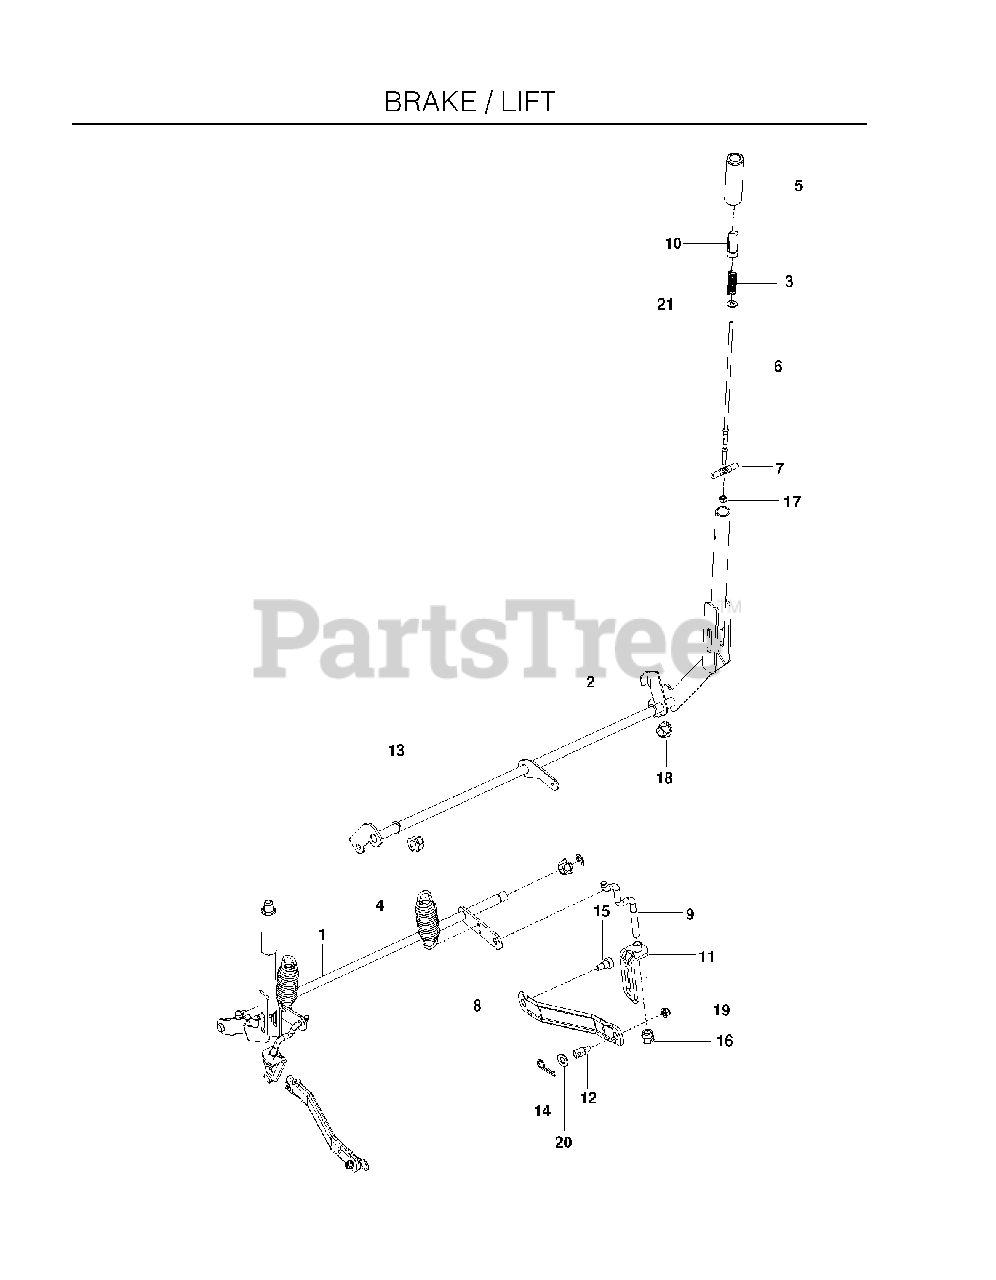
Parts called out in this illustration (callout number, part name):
1	SHAFT, LIFT, BLACK
2	SHAFT ASSY, BRAKE WLDMT, BLK
3	SPRING, COMPRESSION
5	GRIP, HANDLE, BLACK
6	ROD, HANDLE RELEASE
7	ROD, LATCH RELEASE
8	ARM.SUSPENSION.MOWER
9	LINK, REAR SUSPENSION
10	BUTTON, PUSH, BLACK
11	ASSEMBLY, BRKT LINK
12	STUD.FASTNER.W/D.ANTI-
13	5/8 E-RING
14	HAIRPIN #4
15	SB 3/8-16 X 3/8 SKT HD ZD
16	NUT, LIFT LINK 7/16-20
17	NUT 1/4-20 NYLOC
18	PLASTIC NUT
19	5/16-18 NYLOC FLANGE NUT
20	WASHER 5/8 FLAT
21	WASHER 1/4 FLAT
